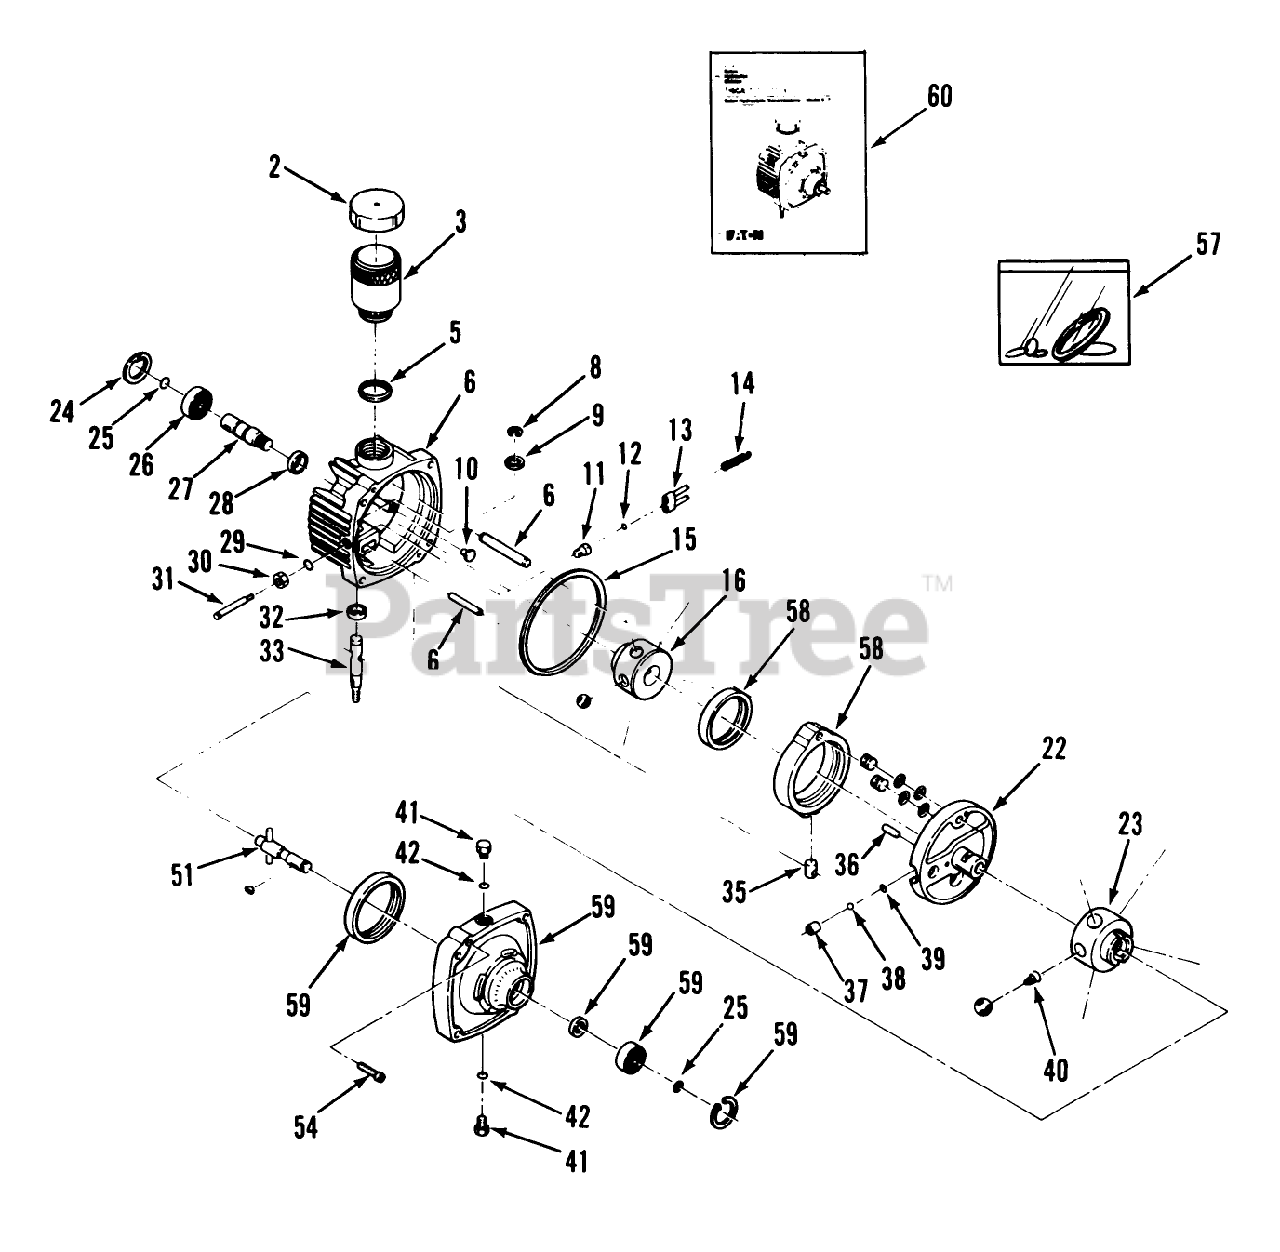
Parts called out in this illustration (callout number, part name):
2	RESERVOIR COVER
3	BODY-RESERVOIR
5	SEAL-RING SQUARE CUT
14	SPRING-VALVE
16	SUB-ASS'Y PUMP ROTOR
25	SNAP-RING
26	BEARING-BALL (INPUT)
27	SHAFT-INPUT
32	SEAL-OIL
57	KIT-OVERHAUL SEALING
59	SUB-ASS'Y BODY
60	Hydrostatic Transmission Repair Manual
